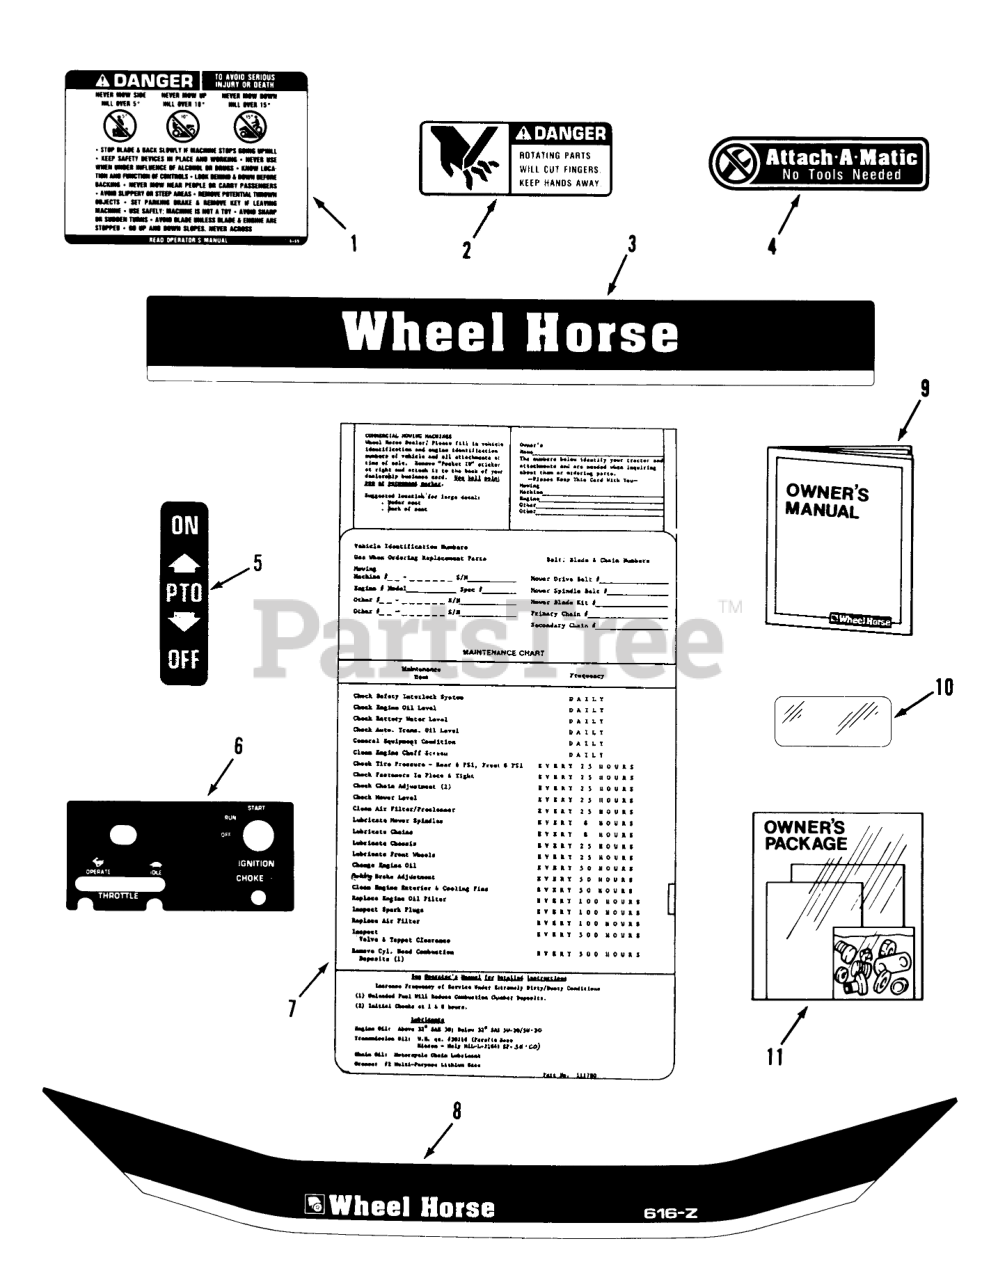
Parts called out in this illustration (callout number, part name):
1	DECAL-DANGER
2	DECAL-DANGER
3	DECAL FRAME REAR
4	Decal-Attac-O-Matic
5	DECAL-PTO
6	DECAL-CONTROL
7	MAINTENANCE-DECAL
8	DECAL FOOTREST FRONT
9	Owner-s Manual
10	DECAL-OVERLAY
11	Loose Parts Package
